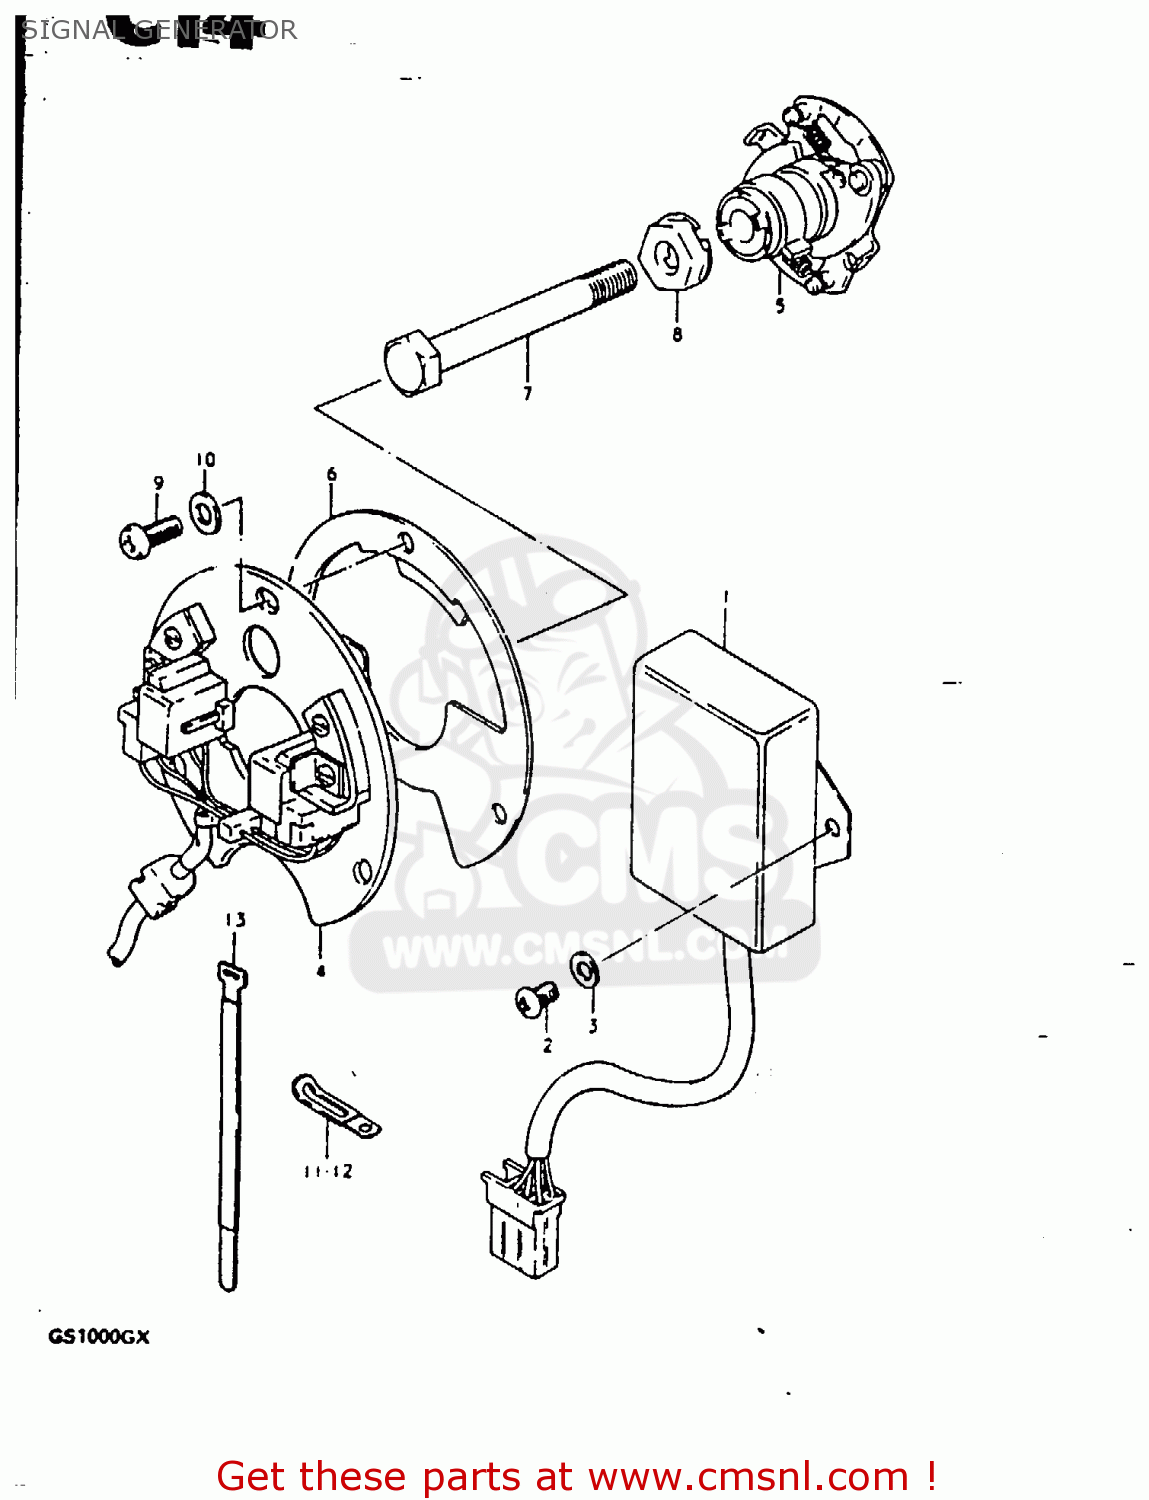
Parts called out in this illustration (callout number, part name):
1	IGNITER UNIT
2	SCREW
3	WASHER
4	SIGNAL GENERATOR ASSEMBLY
5	GOVERNOR ASSEMBLY
6	PLATE,TIMING
7	BOLT
8	WASHER
9	SCREW(5X12)
10	WASHER
11	CLAMP L:35
12	CLAMP
13	CLAMP
